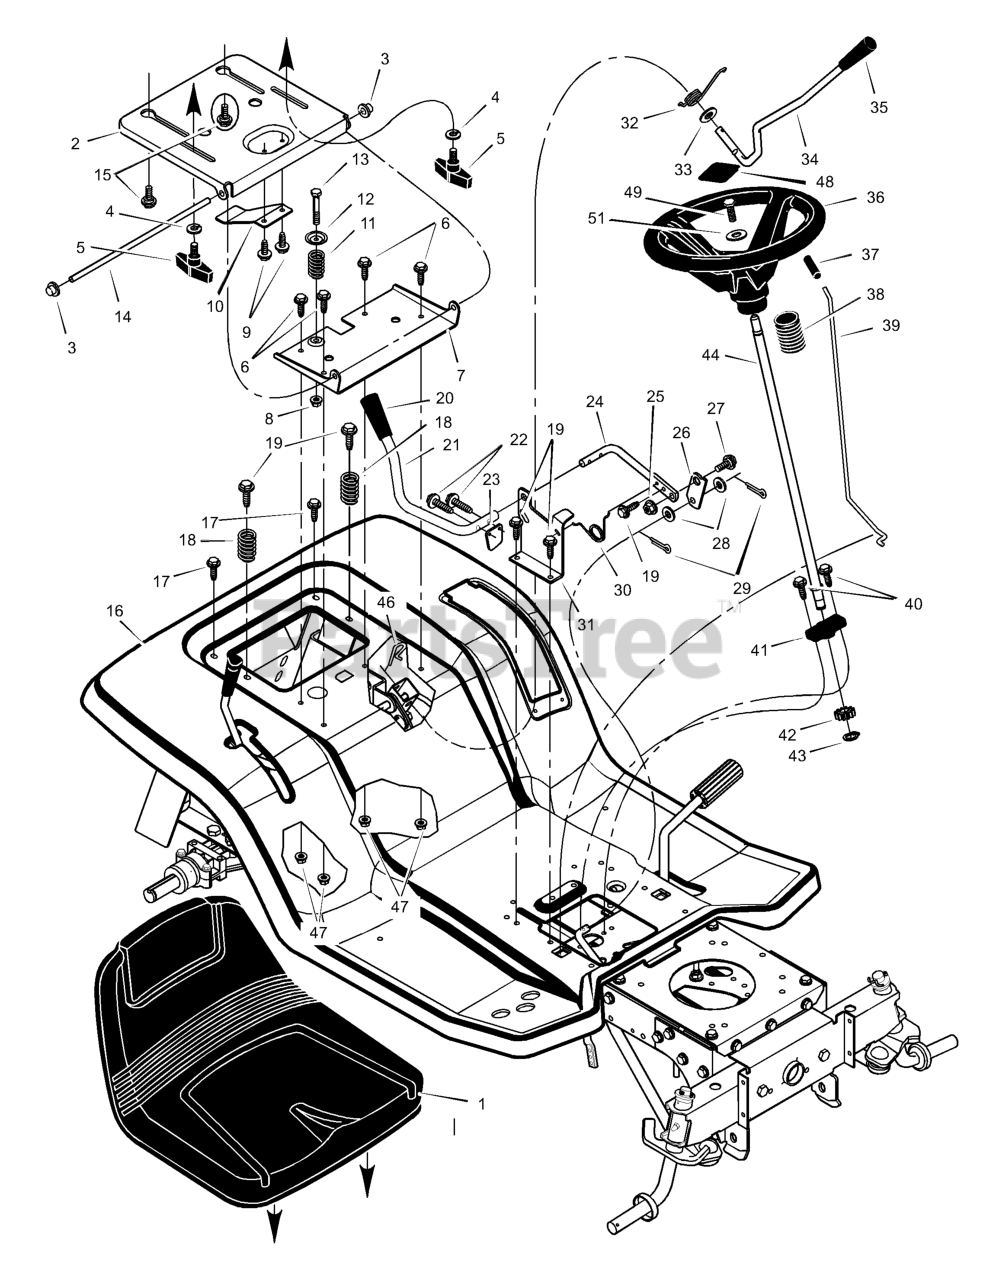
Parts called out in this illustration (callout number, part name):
2	Support, Seat
3	Push-On Cap
4	Washer
5	Bolt, Wing
6	Bolt
7	Bracket, Pivot
8	Nut
10	Spring, Leaf
11	Spring
12	Washer, Cup
14	Rod, Pivot
15	Bolt, Shoulder
16	Deck, Seat
20	Grip
21	Handle, PTO
22	Screw, Hex
23	Paddle, Switch
24	Lever, PTO
25	Nut
26	Link, PTO
27	Shoulder, Bolt
29	Pin, Cotter
31	Bracket, PTO
34	Handle, Lift
35	Grip
36	Wheel, Steering
38	Bellows
39	Rod, Parking Brake
41	Bearing, Lower
42	Gear, Pinion
44	Shaft, Steering
46	Pin, Cotter
47	Nut
48	Insert, Steering Wheel
49	Screw, Hex
51	Washer
